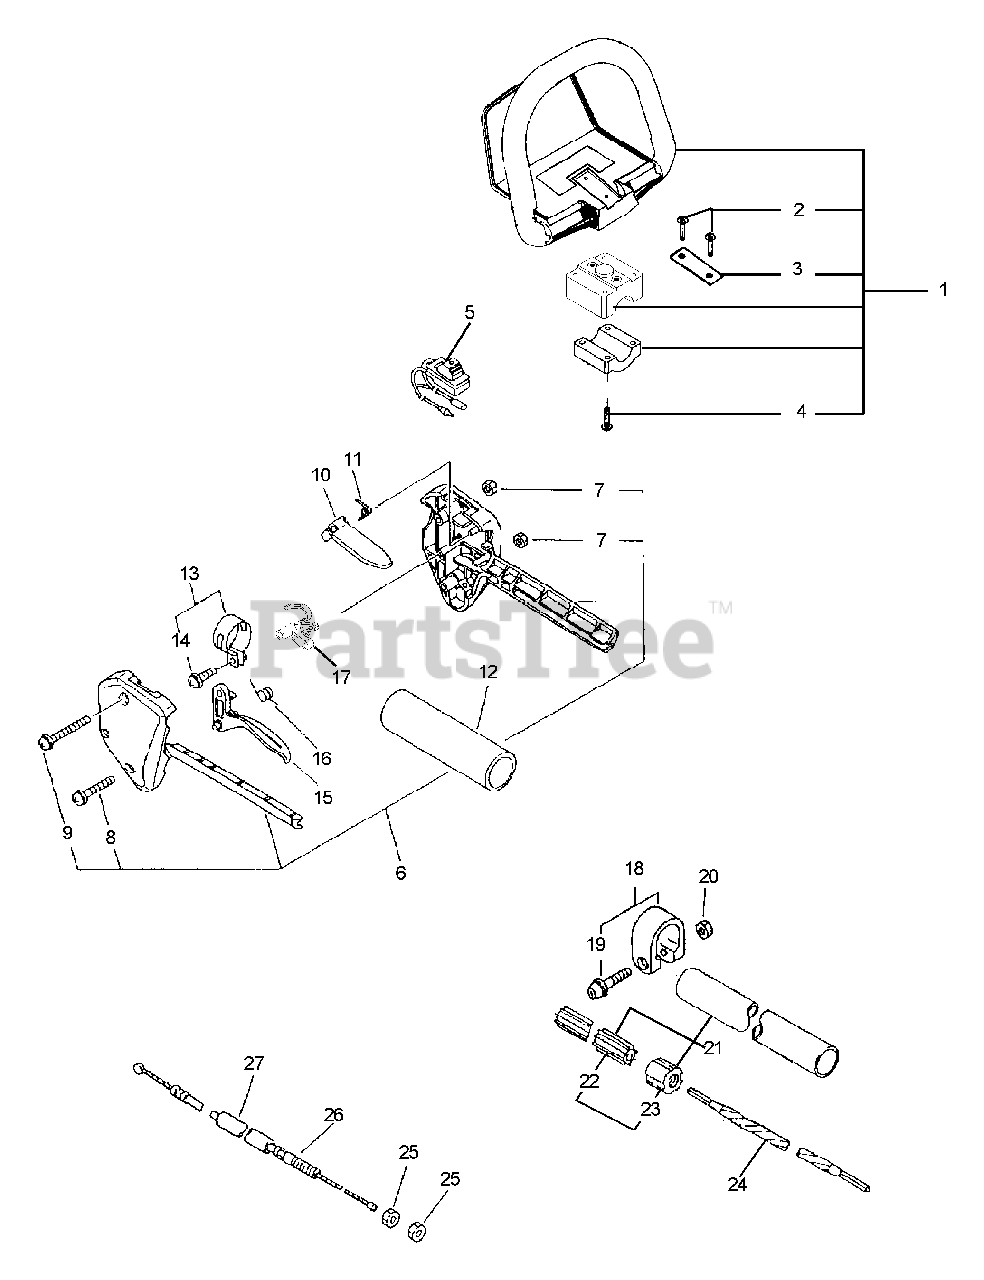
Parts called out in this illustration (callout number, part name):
1	FRONT HANDLE ASSY
2	BOLT 5×30
3	PLATE, EYE
5	SWITCH ASSY, ON-OFF
6	THROTTLE BRACKET SET
7	NUT M5
8	SCREW 5×25
9	SCREW 5×35
10	LEVER, THROTTLE LOCKOUT
11	SPRING, TORSION
12	GRIP, HANDLE
13	BAND
14	SCREW 5×14
15	TRIGGER, THROTTLE
16	SPRING, TORSION
17	LOCKOUT, THROTTLE
18	CLAMP
19	SCREW 5×28
20	NUT M5
21	MAIN PIPE ASSY
22	LINER - FLEXIBLE
24	DRIVESHAFT - FLEXIBLE
26	CABLE, THROTTLE
27	TUBE, PROTECTIVE - CORRUGATED
